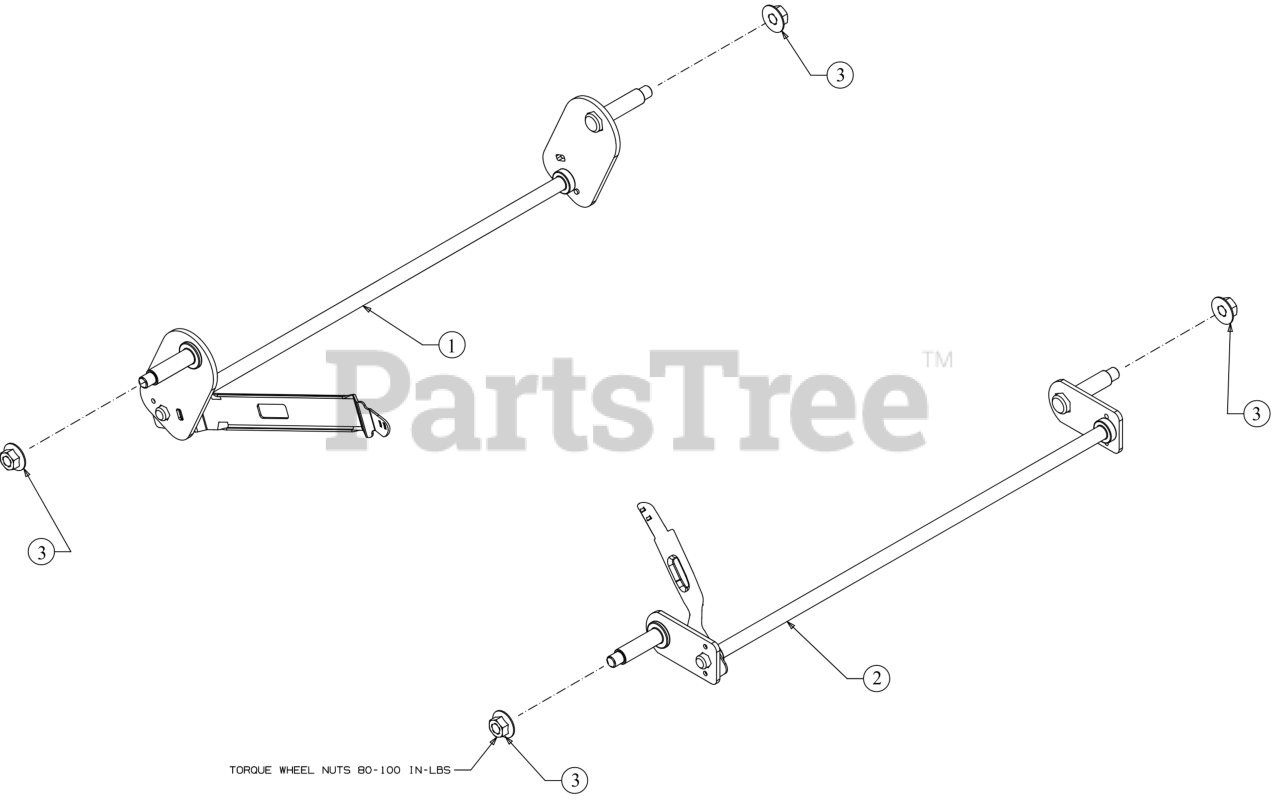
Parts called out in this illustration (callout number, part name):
1	11" REAR AXLE ASSEMBLY
2	7" FRONT AXLE ASSEMBLY
3	FLANGE LOCK NUT
